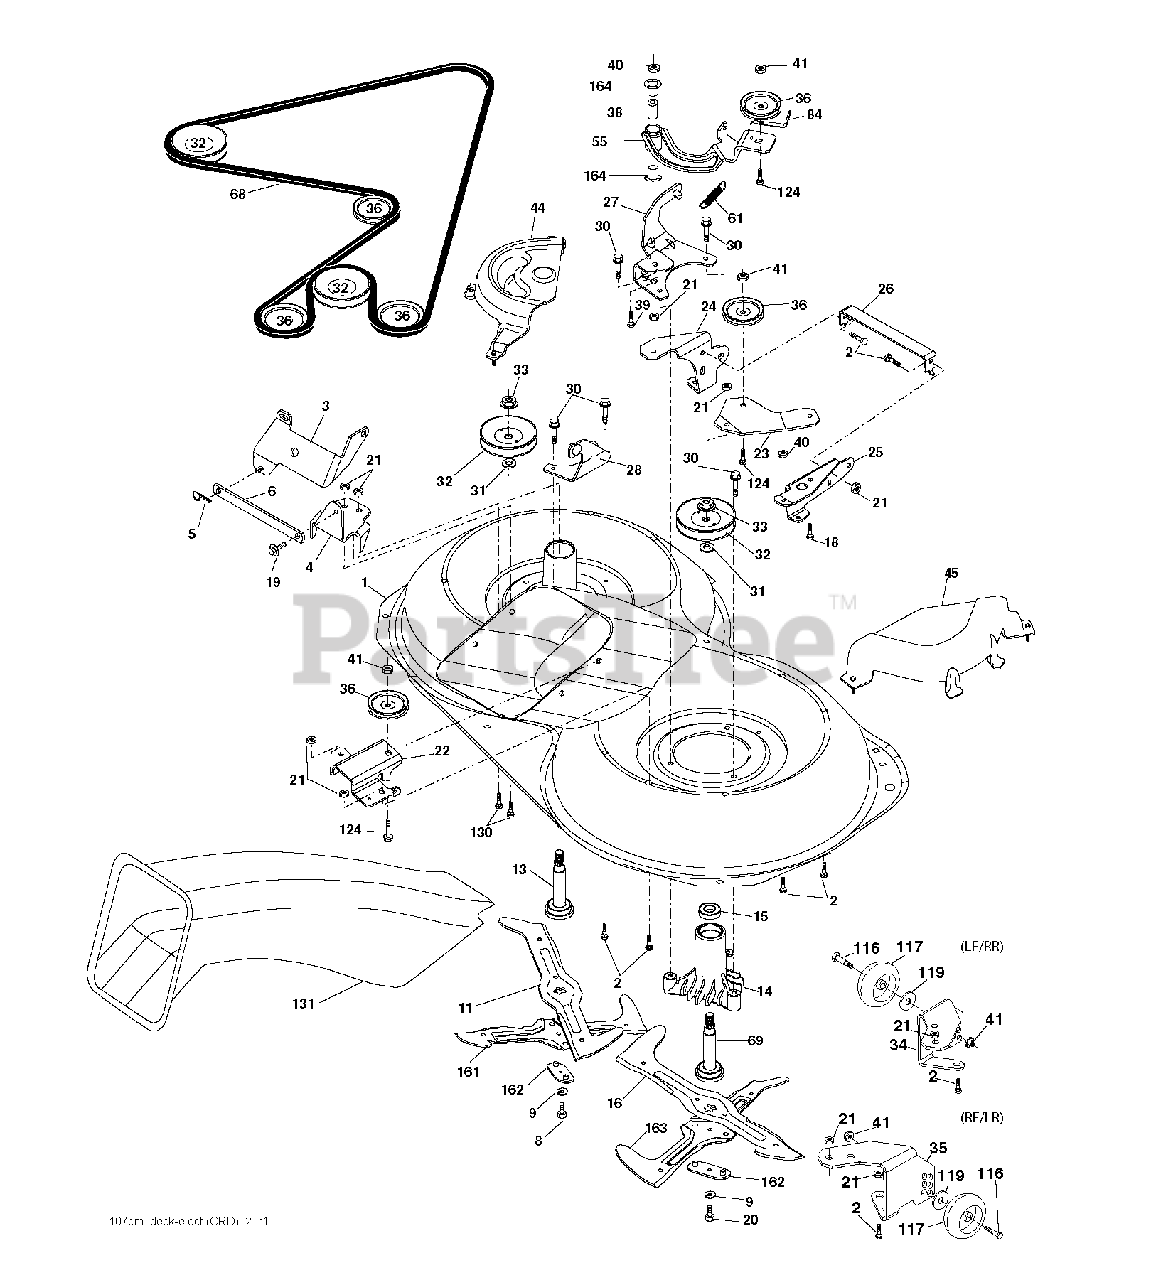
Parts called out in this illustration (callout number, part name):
2	BOLT
3	BRACKET.ASM.BAR.SWAY.CHASS
5	RETAINER-SPRNG RB
6	BAR SWAY
9	LOCKWASHER
11	BLADE.3N1.LH.CRD
13	SHAFT ASM VENT
14	HSG MANDREL
16	BLADE.3N1.RH.CRD
19	BOLT SHD 5/16-18
21	LOCKNUT
22	BRACKET
23	BRACKET
27	BRACKET
30	SCREW, WASHER HEAD
31	WASHER.SPACER.MANDREL
33	NUT.FLANGE.LOCK.TOP
36	PULLEY.IDLER.4.25
40	LOCKNUT
41	NUT LOCK FLG 3/8-16 UNC
55	ARM IDLER
68	HEX-BELT 107 MOWER
69	SHAFT.ASM.W/LWR.BRG.RH.THREAD
84	KEEPER, BELT IDLER
116	BOLT.SHOULDER.3/8-16X3-5/8
117	WHEEL. GUAGE RALLY
124	BOLT.3/8-16X1.50
131	CHUTE BAGGER
164	BRNG T
